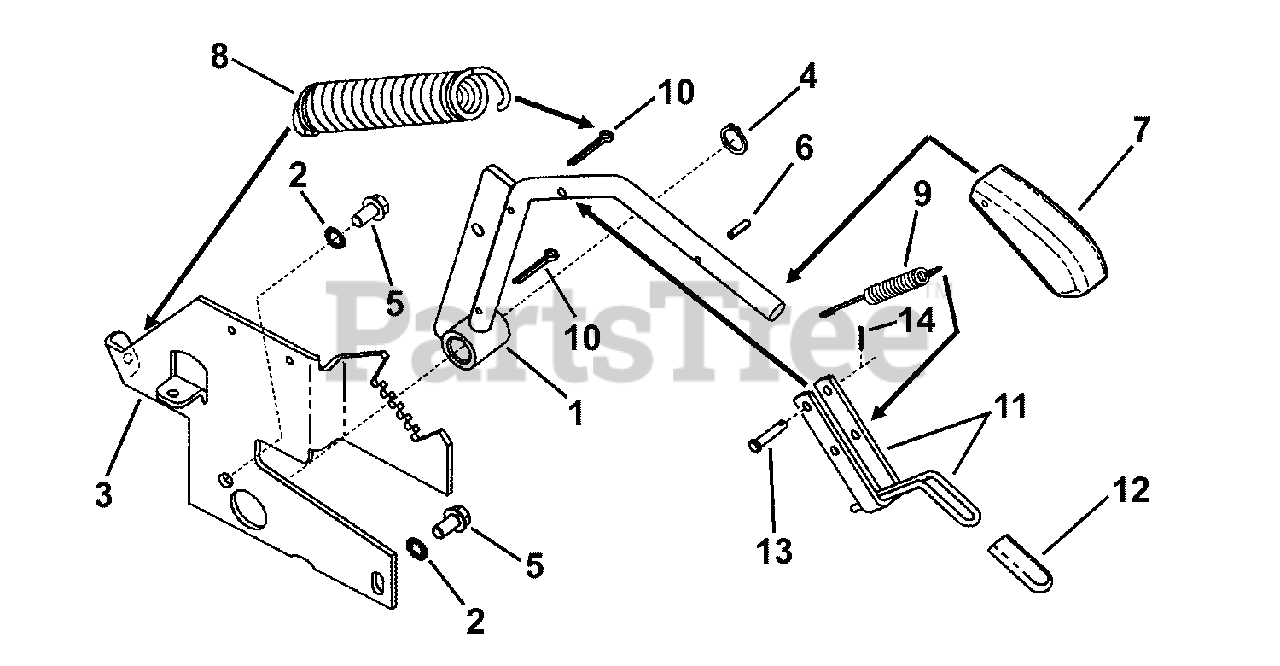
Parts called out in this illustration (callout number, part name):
1	LEVER, Height Adjustment Lift (weldment)
2	WASHER, 3/8" Internal Tooth Lock
3	QUADRANT, Lift Lever
4	RING, .625 External Retaining
5	SCREW, 3/8-16 x 3/4" Hex Washer Self-Tap
6	ROLL PIN, 3/16 x 3/4"
7	GRIP,Deck Height Adjustment Lever
8	SPRING, Extension
9	SPRING,Latch
10	PIN, 3/16 x 1-1/2" Cotter
11	LATCH (weldment)
12	GRIP, Lift Latch
13	PIN, 1/4 x 1-1/4" Clevis
14	PIN, 1/16 x 3/4" Cotter
